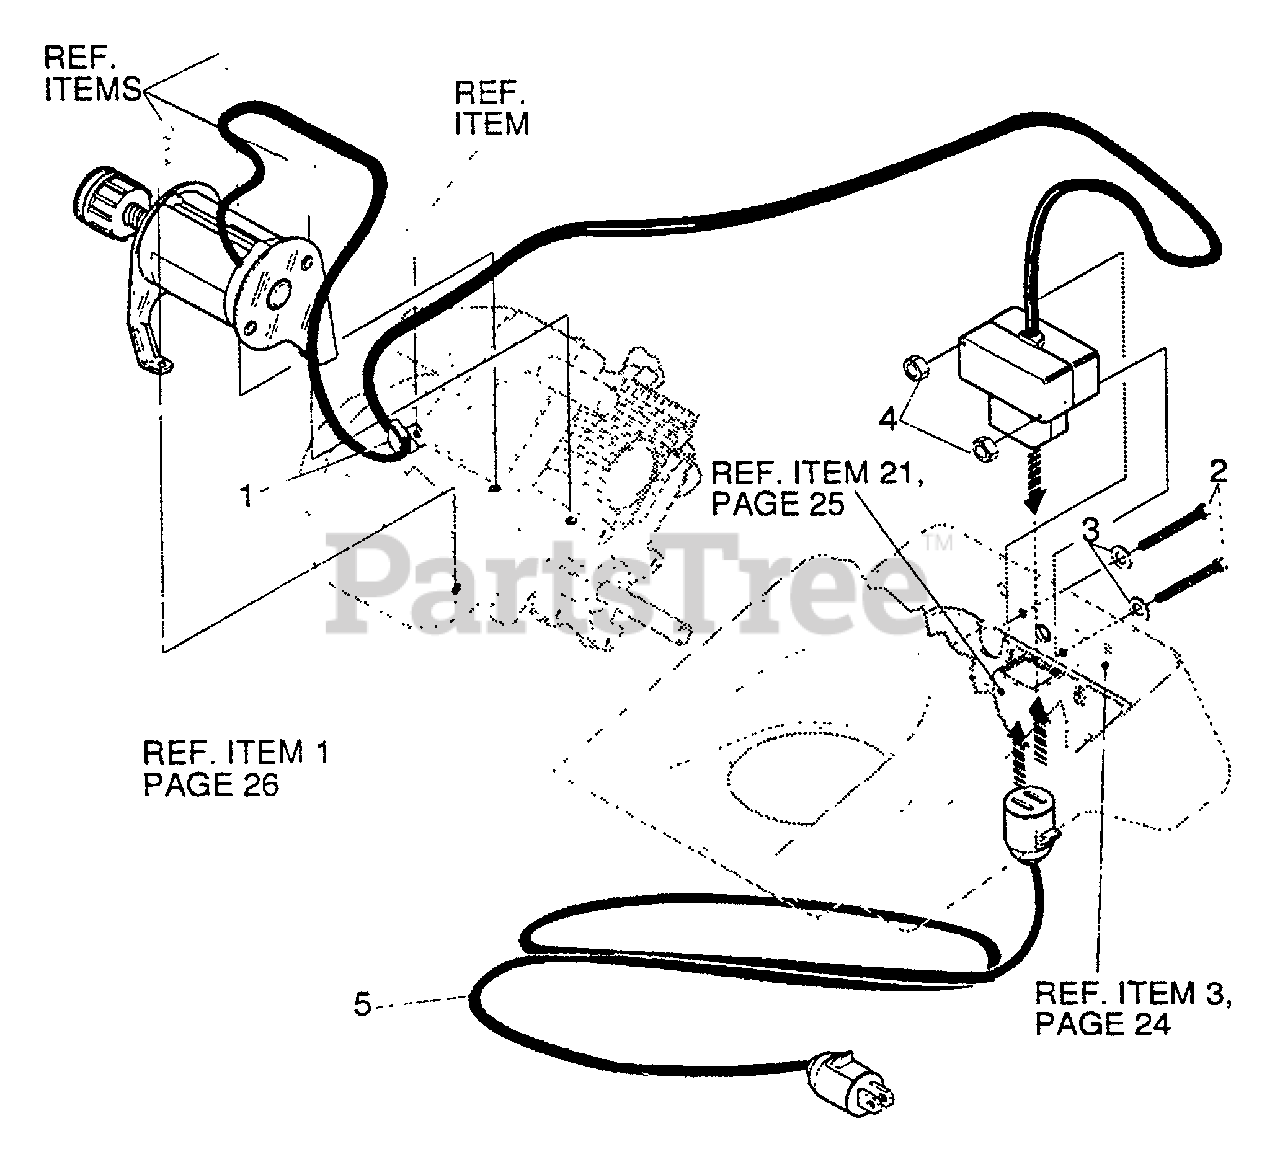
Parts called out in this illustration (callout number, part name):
1	RETAINER, WIRE
2	SCREW - 8-32 X 3"
3	WASHER - .188 X .38 X .040"
4	NUT - 8-32 -- KEPS
5	CORD, EXTENSION 10 FEET
